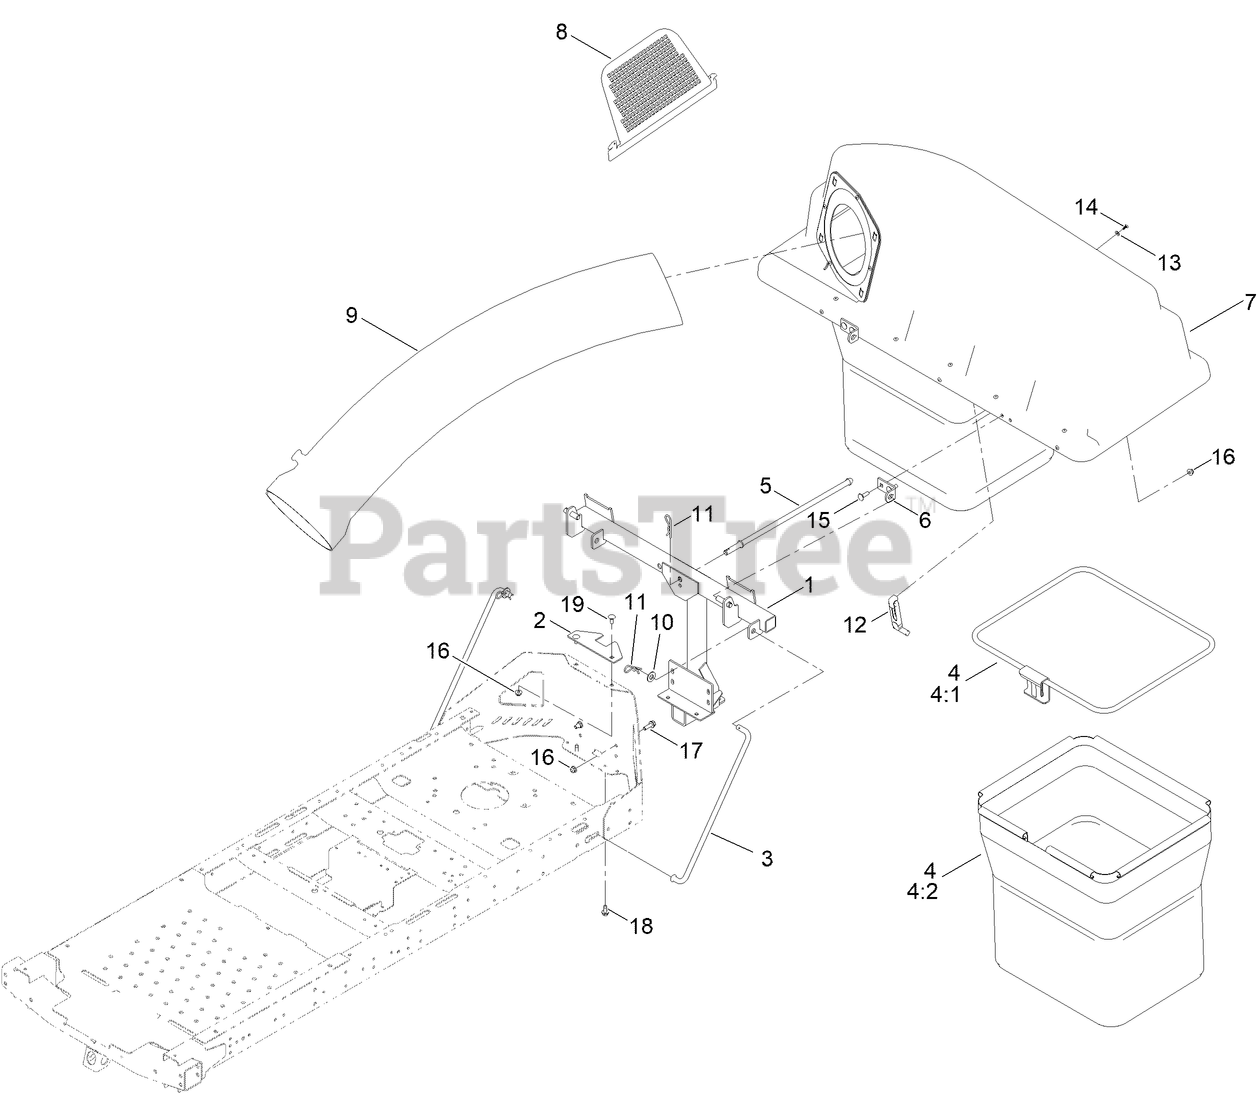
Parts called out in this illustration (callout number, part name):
1	FRAME-PIVOT
2	BRACKET-STABILIZER
3	ROD-SUPPORT, CZ
4	BAG ASM
4:1	FRAME, BAG [BLACK]
4:2	BAG ASM 20IN DEPTH
5	ROD-HOOD, DOWN (HOLD)
6	BRACKET-HOPPER PIVOT
7	TOP ASM-BAGGER
8	SCREEN-BAGGER
9	TUBE-BAGGER
10	WASHER-FLAT
11	PIN-HAIR
12	LATCH-RUBBER
13	WASHER-PLAIN
14	SCREW-PLASTIC, PTH
15	BOLT-CARR
16	NUT-HF
17	SCREW-HHF
18	SCREW-HWHTF
19	BOLT-CARR
